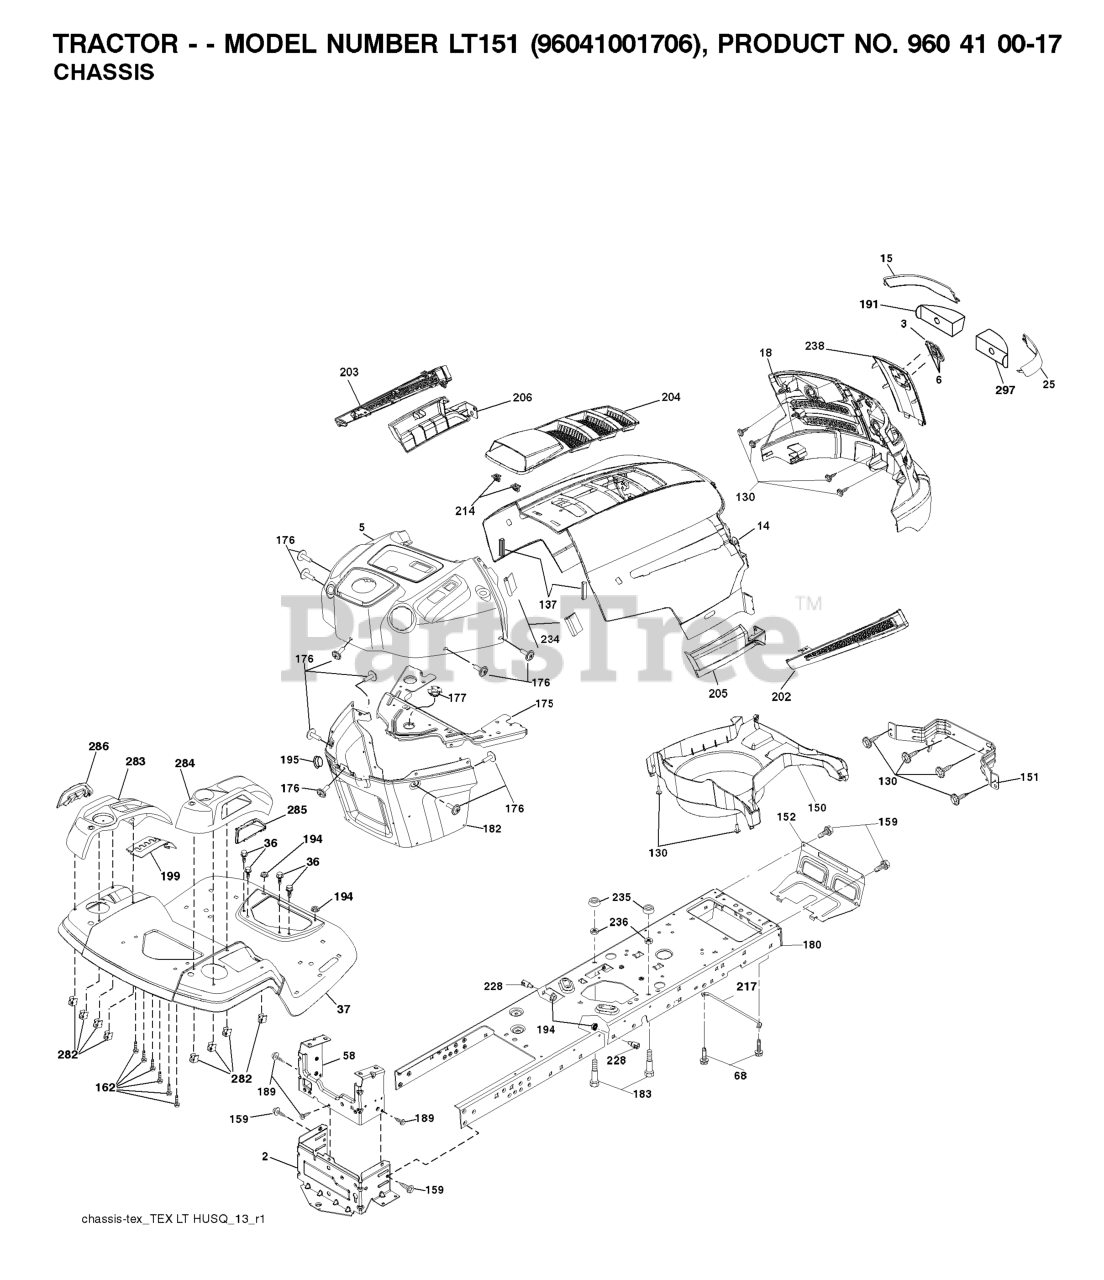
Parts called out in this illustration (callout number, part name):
2	DRAWBAR.LOWER.2PC.18/22
3	RP LOGO
5	DASH
14	HOOD
15	LENS.HUSQVARNA LT.LH
18	RP GRILLE/LENS ASM.
25	LENS.HUSQVARNA LT.RH
36	SCREW 5/16"
37	RP FENDER.TLT.FS.W/CPH.422
58	DRAWBAR UPPER 2PC SMALL FENDER
68	Screw 5/16-18 x 1/2 Hex, Self Tapping 5/16-18 x 1/2
130	SCREW.#10 X 0.750.BOS
137	BUMPER DASH
151	BRACKET PIVOT
152	SHIELD.BROWNING/DEBRIS
159	SCREW, 3/8-16X3/4
162	SCREW.HI-LO.CONSOLE
175	CROSSMEMBER
176	SCREW.#10-24X5/8.RN.QU
177	BUSHING STEERING
180	CHASSIS.STAMPING.LT/GT
182	DASH.LOWER.PREDATOR LT
183	BOLT.5/16-18X1-1/4 FULL.THREAD
189	SCREW
191	INSERT REFLECTIVE
194	NUT LOCK HEX FLANGE 5/16-18
195	PLUG DASH
199	PLATE.DECK.LIFT.HUSQ.LT
202	VENT SIDE HOOD RH
203	VENT SIDE HOOD LH
204	VENT TOP HOOD
205	SKIRT SIDE RH
206	SKIRT SIDE LH
214	CLIP.RETAINER.TINNER.
217	ROD.PIVOT.HOOD
228	STUD.FASTNER.W/ANTI-ROTATE
234	BUMPER.HOOD.TEX.HUSQVARNA
235	SPACER FENDER
236	NUT.CENTERLOCK.5/16-
238	TRIM
282	CLIP.RETAINER.CONSOLE.LT.HUSQ
283	CONSOLE.DECK.LIFT.HUSQ.N/FR.GR
285	CONSOLE INSERT RH
286	CONSOLE.INSRT.LH.HUSQ.LT.BLACK
287	SCREW 1/4X20
